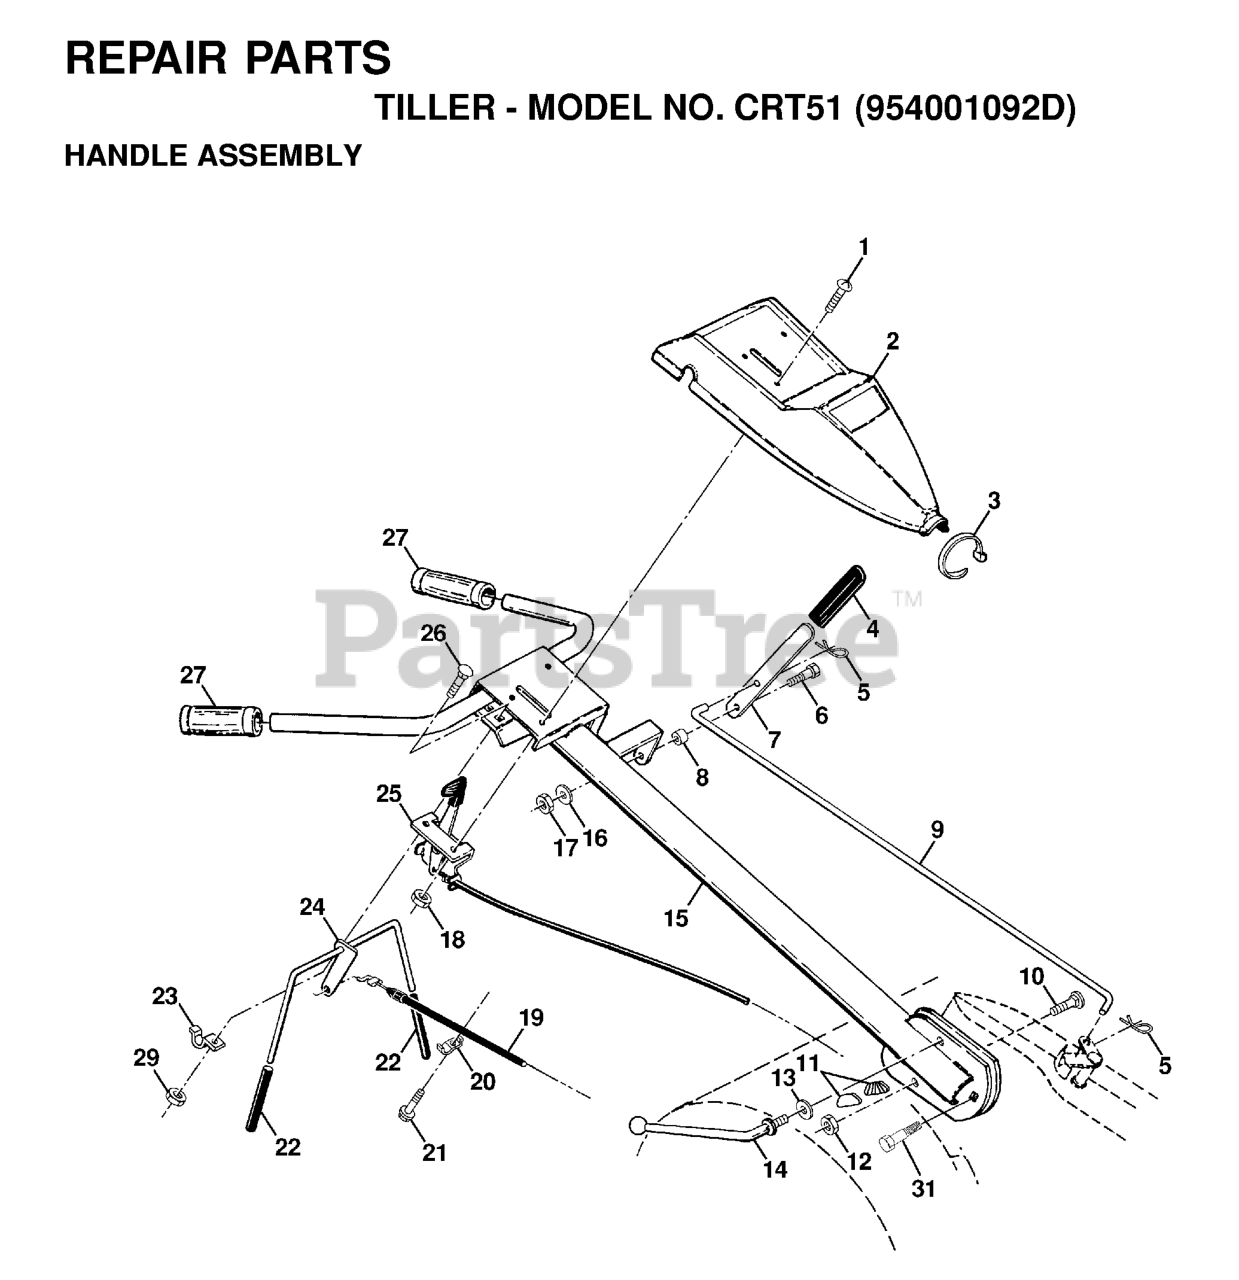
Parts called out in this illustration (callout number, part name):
1	SCREW.PNHD.10-24
3	TIE CABLE CRT
4	GRIP T
5	RETAINER M
6	SHOULDER BOLT ST
7	SHIFT HANDLE CRT
8	GROMMET.RUBBER.CRT.TILLER
9	SHIFT ROD CRT
10	BOLT D
11	LOCK.HANDLE.CRT
12	LOCKNUT
13	WASHER CRT
14	LEVER.LOCK.CRT
15	HANDLE
16	LOCKWASHER
17	NUT
18	NUT **
19	CABLE, CLUTCH 48 "Z"
20	CONDUIT.CLIP.PLATED
21	TAPPING SCREW
22	GRIP BAR CRT(1)
23	CLAMP.BAR.CRT.BLACK
24	BAR ASSY CONTROL
25	CONT,THROTTLE
27	KIT.GRIP.HANDLE.5.00.BLK.VINYL
31	BOLT.PIVOT
